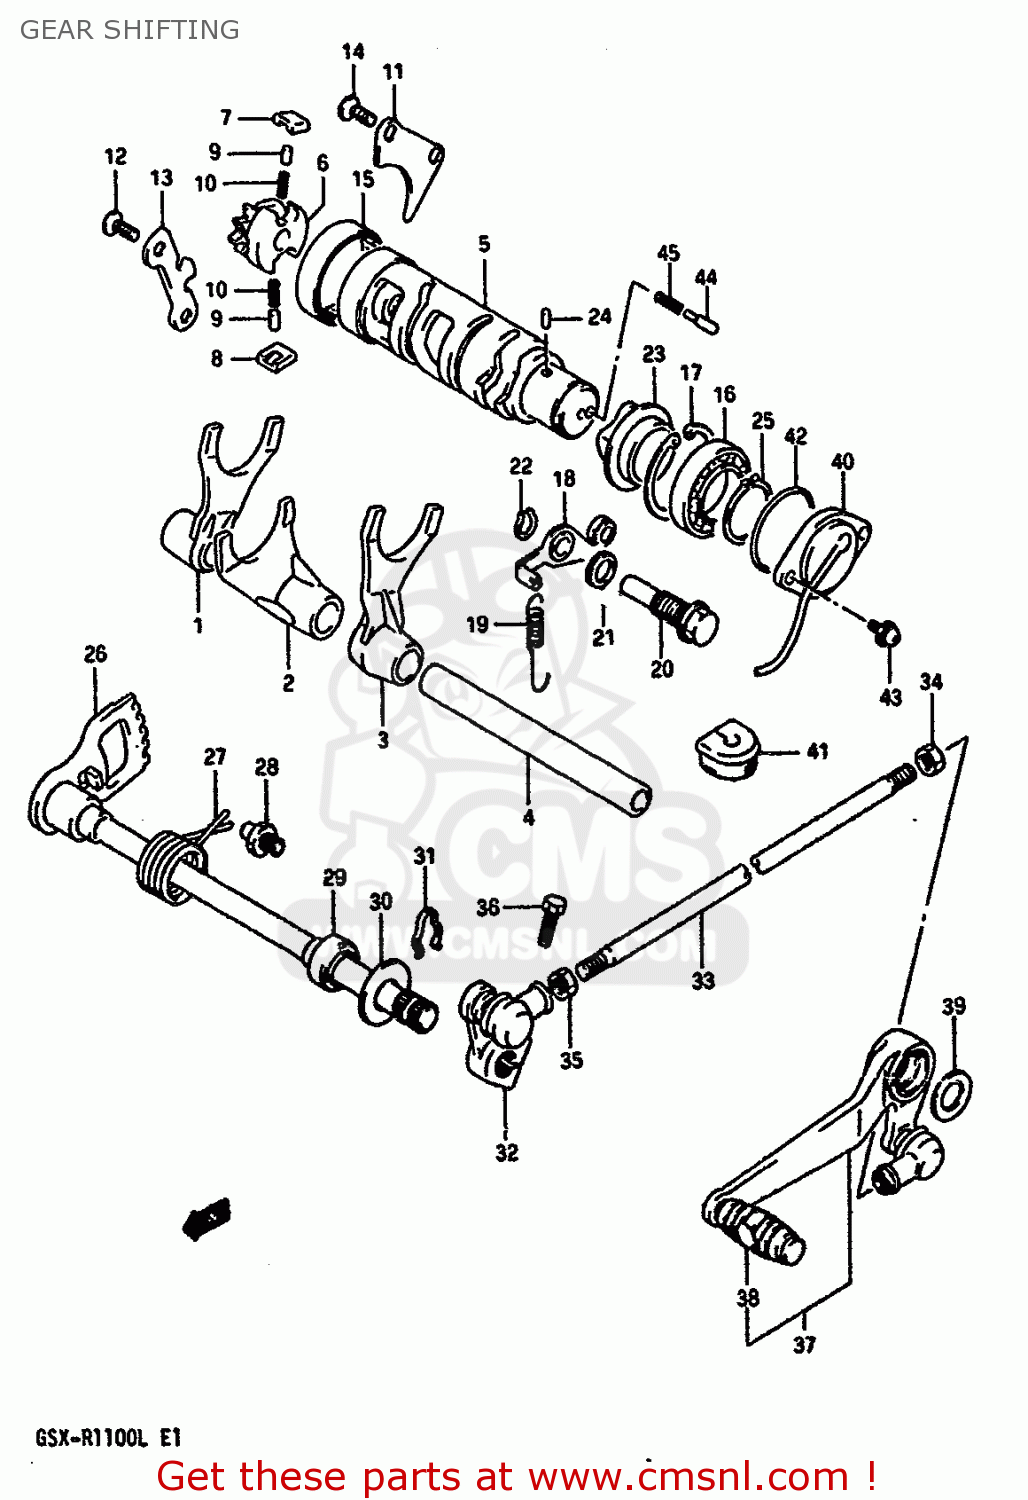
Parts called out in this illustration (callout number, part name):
1	FORK,GEAR SHIFT NO.1
2	FORK,GEAR SHIFT NO.2
3	FORK,GEAR SHIFT NO.3
4	SHAFT,GEAR SHIFT FORK(L:128)
5	CAM,GEAR SHIFT
6	GEAR,GEARSHIFT CAM DRIVE
7	PAWL,GEAR SHIFT NO.1
8	PAWL,GEAR SHIFT NO.2
9	PIN(5X8)
10	SPRING
11	LIFTER,GEAR SHIFT PAWL
12	SCREW
13	GUIDE,GEAR SHIFT CAM
14	SCREW
15	BEARING(43X49X12)
16	BALL BEARING
17	CIRCLIP,42MM
18	STOPPER,GEAR SHIFT CAM
19	SPRING
20	SHAFT,GEAR SHIFT CAM STOPPER
21	GASKET(10X14X3.6) (NAS)
22	CIRCLIP
23	PLATE,STOPPER
24	PIN 4X6
25	CIRCLIP,25MM
26	SHAFT,GEAR SHIFT
27	SPRING
28	STOPPER,GEAR SHIFT CAM
29	OIL SEAL
30	WASHER (12.5X27X1.6)
31	SPRING,RETAINER
32	ARM,GEAR SHIFT
33	ROD,GEAR SHIFT LINK
34	NUT
35	NUT 6MM
36	BOLT
37	LEVER ASSEMBLY,GEAR SHIFTING
38	RUBBER,GEAR SHIFT PEDAL
39	WASHER(18X24X1)
40	TERMINAL BASE ASSY,NEUTRAL
41	GROMMET,LEADWIRE
42	O RING(D:2.4,ID:36.5)
43	SCREW
44	PIN(5X15.5)
45	SPRING
